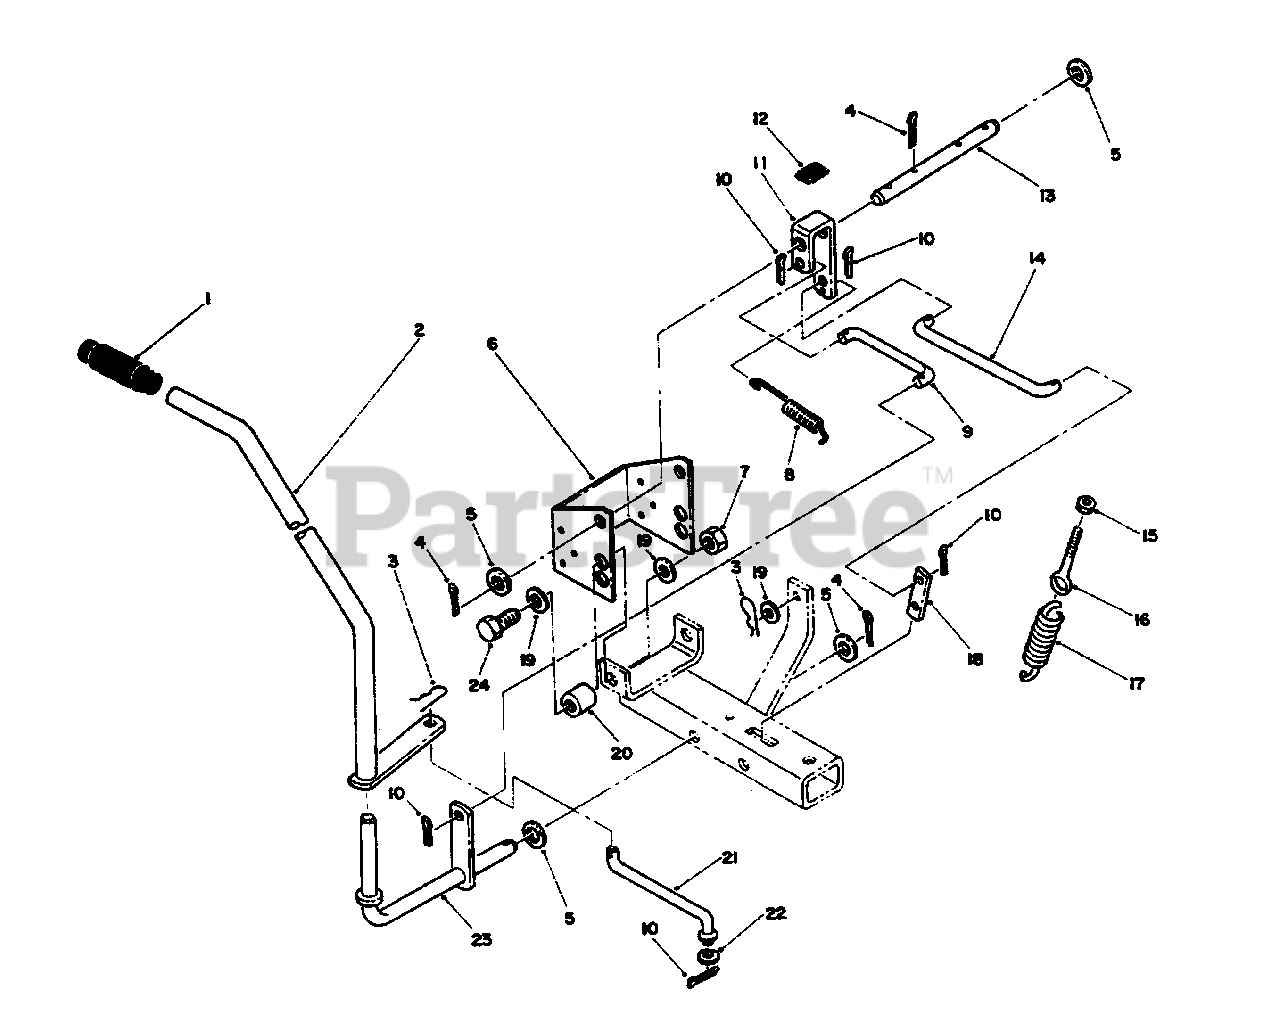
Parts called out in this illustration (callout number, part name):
2	Handle
3	Pin-Hairpin
4	Pin-Cotter
5	Washer-Flat
6	Brace-Mounting
7	Nut-Lock
9	Rod-Bellcrank
10	Pin-Cotter
11	Bellcrank
12	Pad-Rubber
13	Shaft
14	Rod-Latch
15	Nut Jam
16	Eyebolt
17	Spring
18	Latch
19	Washer-Flat
20	Spacer
22	Washer-Flat
23	Pivot-Handle
24	Screw-Hex Hd. Cap
